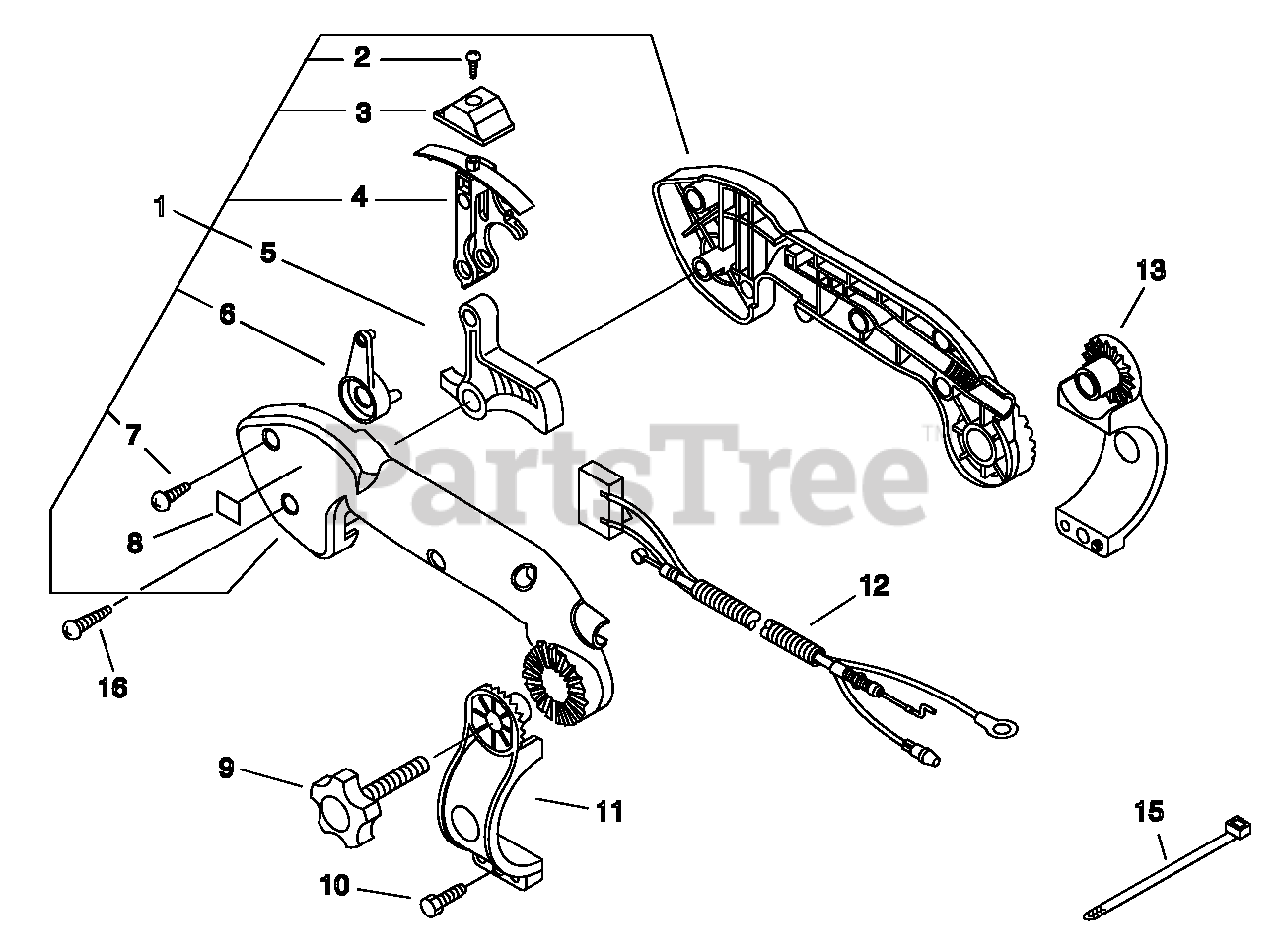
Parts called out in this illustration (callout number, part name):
1	CONTROL HANDLE ASSY
1	HANDLE ASSY - FRONT
2	SCREW - 3X14
3	KNOB, THROTTLE CONTROL
4	LEVER, THROTTLE CONTROL
5	TRIGGER, THROTTLE
6	LEVER, THROTTLE
7	SCREW - 5X20
8	LABEL - CAUTION
9	THUMBSCREW
10	SCREW - 5X20 -- TAPPING
11	BRACKET, HANDLE - RIGHT
12	CONTROL CABLE ASSY
13	BRACKET, HANDLE - LEFT
15	TIE, CABLE - SMALL
16	SCREW - 5
